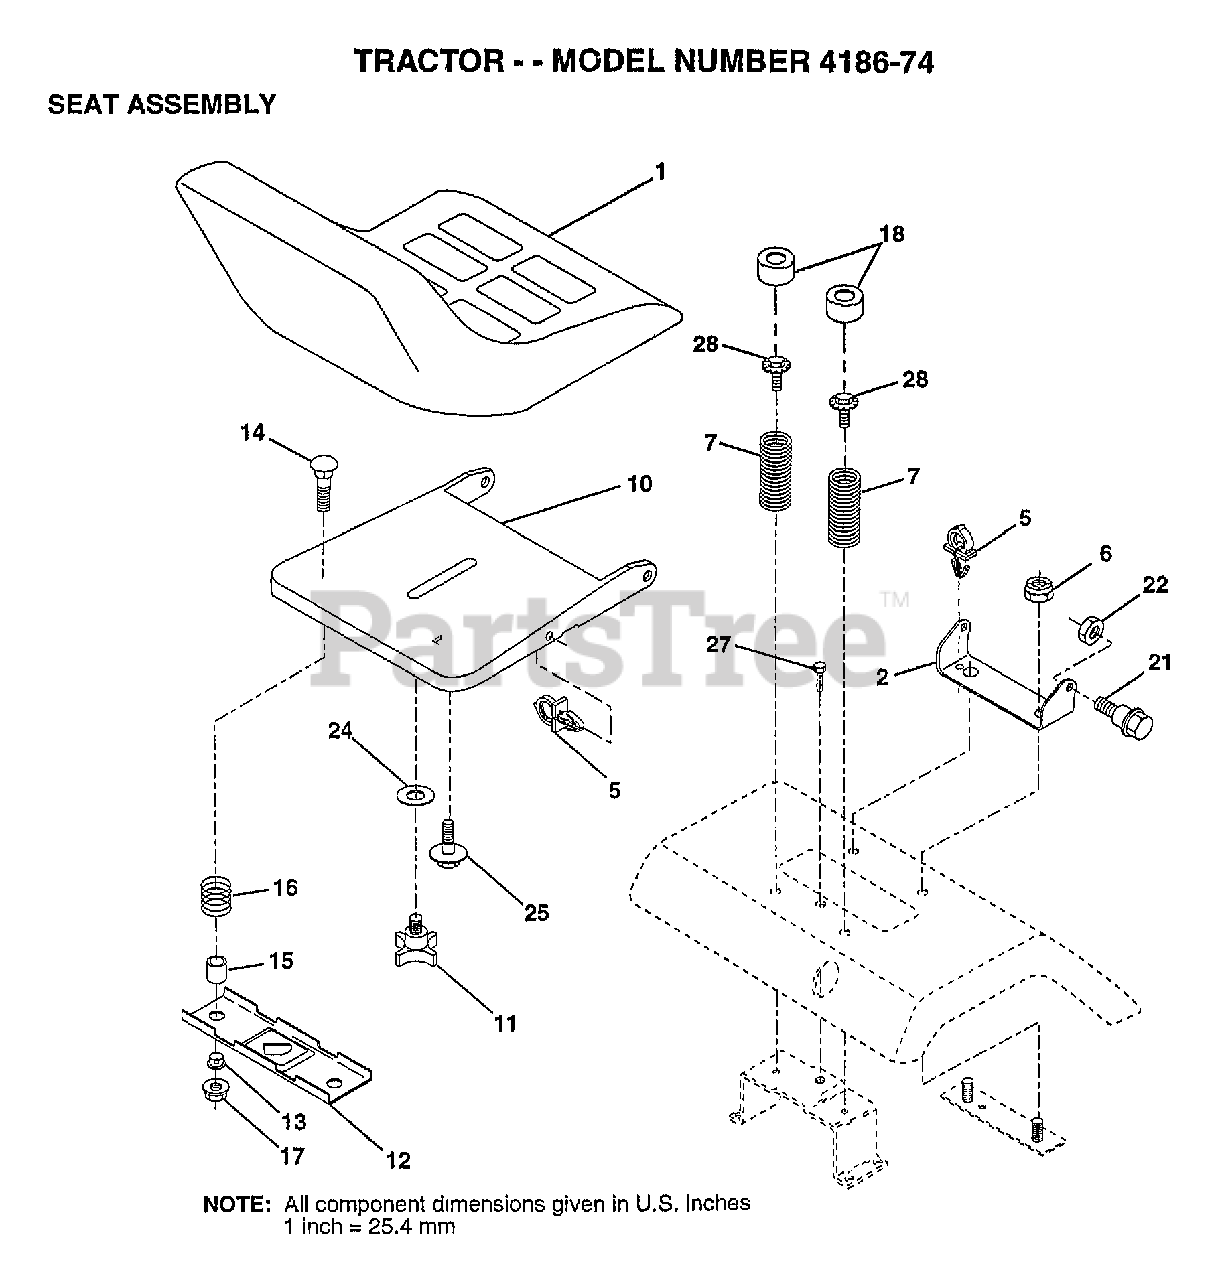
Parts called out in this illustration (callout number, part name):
2	BRACKET PVT SEAT
5	CLIP.PUSH-IN.HING
6	NUT
7	SPRING COMPRESSIO
10	PAN-SEAT
11	"KNOB 1/2"" YT"
12	BRKT SWITCH
13	BUSHING
15	SPACER SPLIT
16	SPRING COMPRESSED
18	CAP SPRING
21	"BOLT,SHOULDER"
24	WASHER
25	"BOLT,SHOULDER"
27	SCREW LT
28	BOLT.5/16-18.UNC
